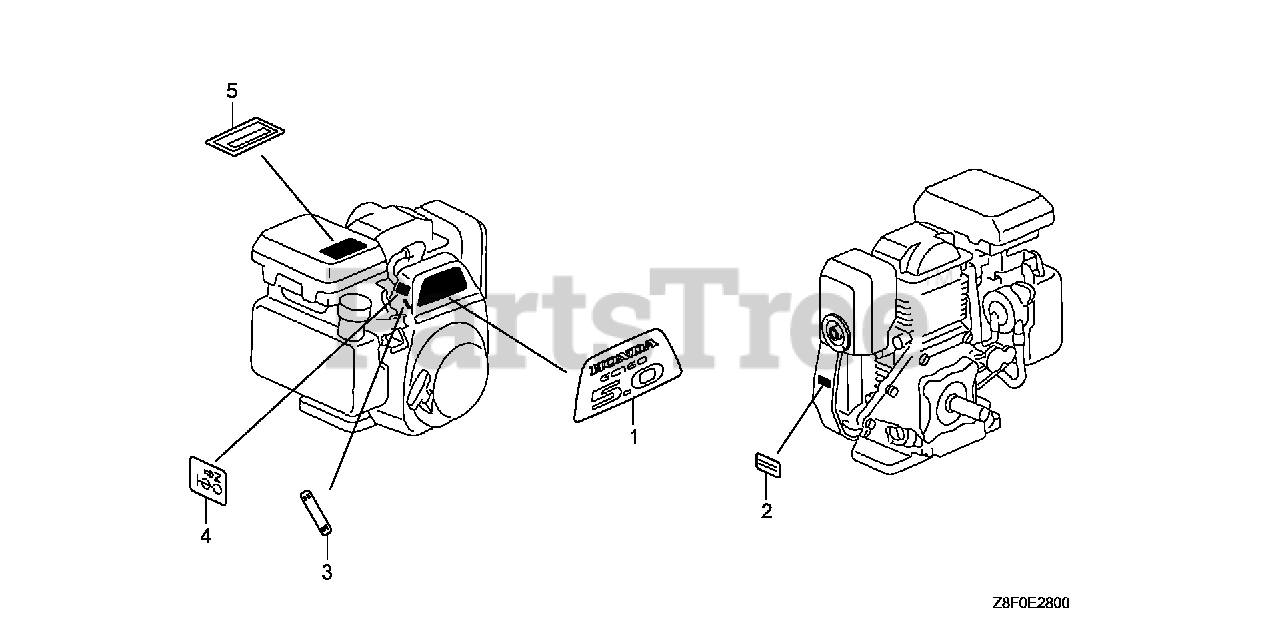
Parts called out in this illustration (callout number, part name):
1	EMBLEM (GC160)
2	LABEL, WARNING (NOT CERTIFIED FOR SALE)
3	MARK, ENGINE SWITCH INDICATION
4	MARK, CHOKE
5	MARK, OIL ALERT (ENGLISH)
